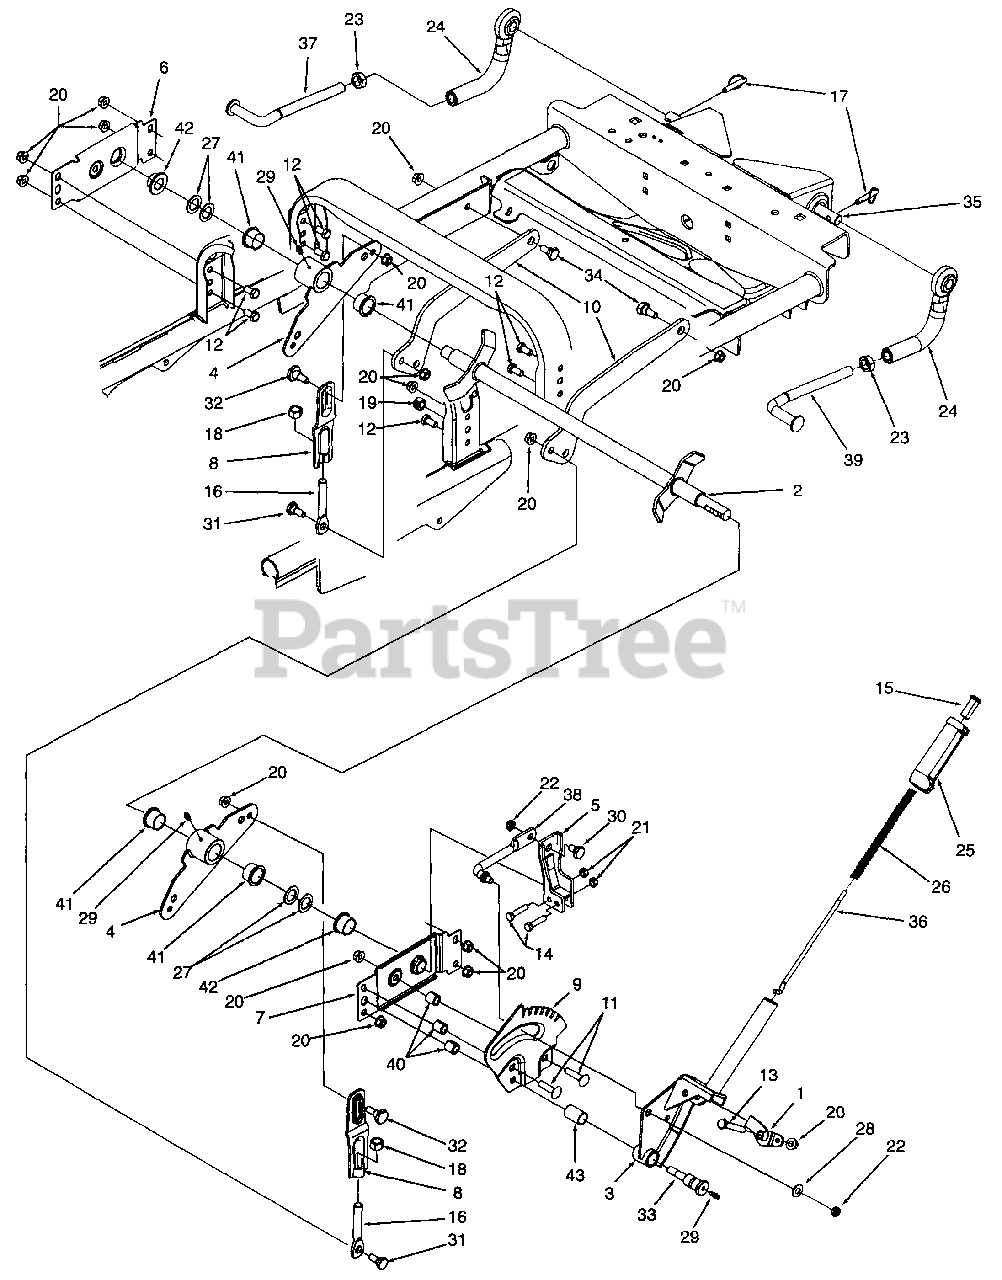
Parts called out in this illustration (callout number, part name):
7	Bracket, Shaft Mtg. RH
11	Bolt, Carriage, 3/8-16 x 1.5
12	Screw, Hex Cap, 3/8-16 x .75 GR5
13	Screw, Hex Cap, 3/8-16 x 2-1/4
14	Screw, Hex Cap, 5/16-18 x 1.38 GR5
15	Button, Handle
16	Link, Eye Bolt Adjustment
17	Clevis Pin, w/ Detent Ball
18	Nut, Hex, 1/2-13
19	Nut, Hex Center Lock, 7/16-14
20	Nut, Hex Flange Lock, 3/8-16
21	Nut, Hex Center Lock, 5/16-18
22	Nut, Hex Insert Lock Jam 3/8-16
23	Nut, Hex Jam, 5/8-18
24	Link, Parallel
25	Grip, Deck Lift Handle
26	Spring, Compression
27	Washer, Flat, .79 x 1.24 x .06
28	Washer, Flat, .406 x .875 x .06
29	Fitting, Grease
30	Bolt, Shoulder
31	Bolt, Shoulder
32	Bolt, Shoulder
33	Bolt, Lift Handle Shoulder
34	Bolt, Shoulder
35	Rod, Parallel Link Front Mtg.
36	Rod, Lift Handle
37	Rod, Connecting LH
38	Rod, Lift Link
39	Rod, Connecting RH
40	Spacer, .448 x .688 x .673
41	Bearing, Flange, 1.0 ID
42	Bearing, Flange, .75 ID x 1.0 OD
43	Bearing, Sleeve, .75 x .875 x 1.25
